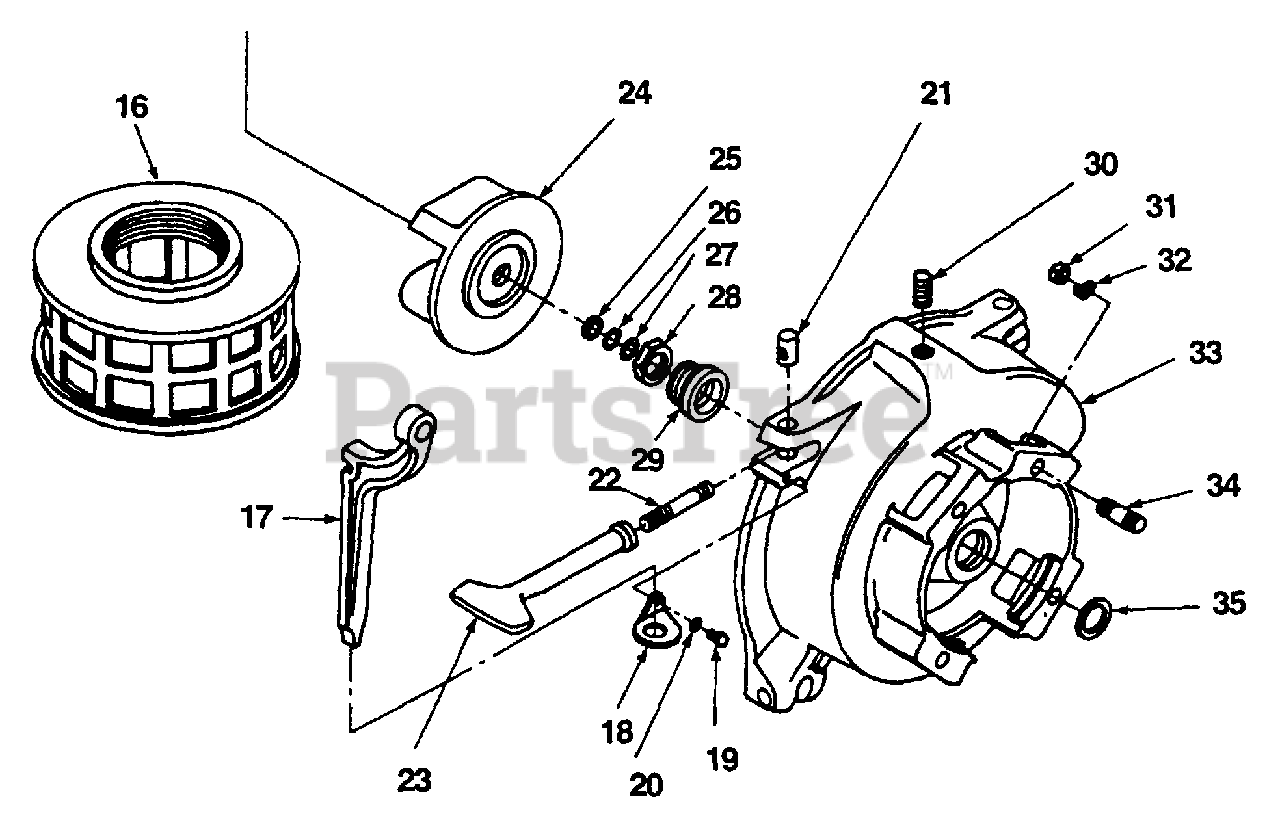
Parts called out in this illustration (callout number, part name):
16	STRAINER
17	SPANNER WRENCH
18	WRENCH HOLDER
19	HEX HD SCREW
20	FLAT WASHER (1/4)
21	HANDLE PIVOT
22	HANDLE STUD
23	DISCONNECT HANDLE
24	IMPELLER
25	SHIM (.010)
26	SHIM (.015)
27	SHIM (.032)
28	HEX NUT
29	SHAFT SEAL
30	SET SCREW (5/8-11 X .75)
31	HEX NUT (7/16-14)
32	LOCKWASHER (7/16)
33	IMPELLER HOUSING
34	STUD (7/16-14)
35	SLINGER
